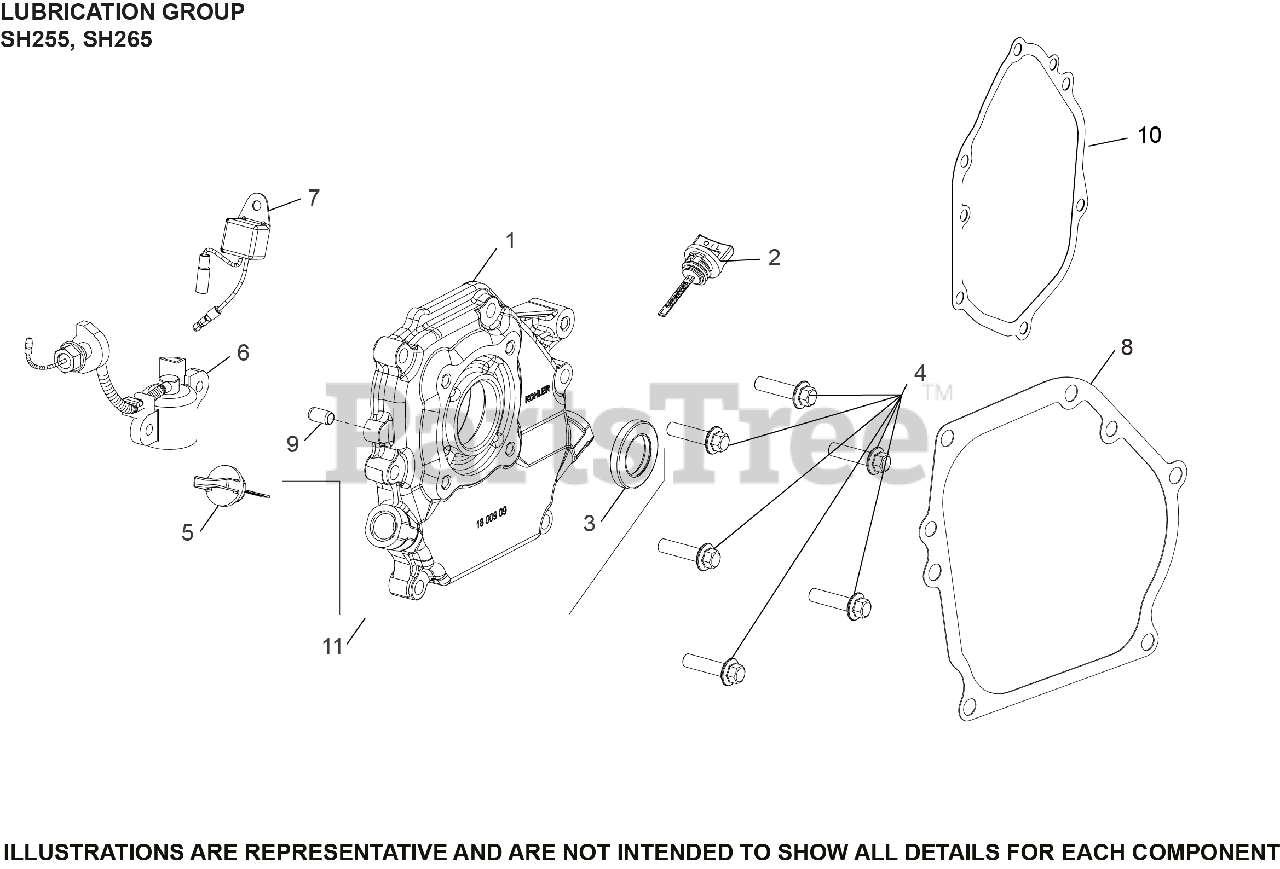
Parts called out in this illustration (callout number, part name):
1	PLATE, CLOSURE & BEARING
2	DIPSTICK ASSEMBLY
3	SEAL, OIL
4	SCREW, CLOSURE PLATE
6	SWITCH, OIL SENSOR ASSEMBLY
7	CONTROL, OIL ALERT UNIT
9	PIN, DOWEL (8MM)
